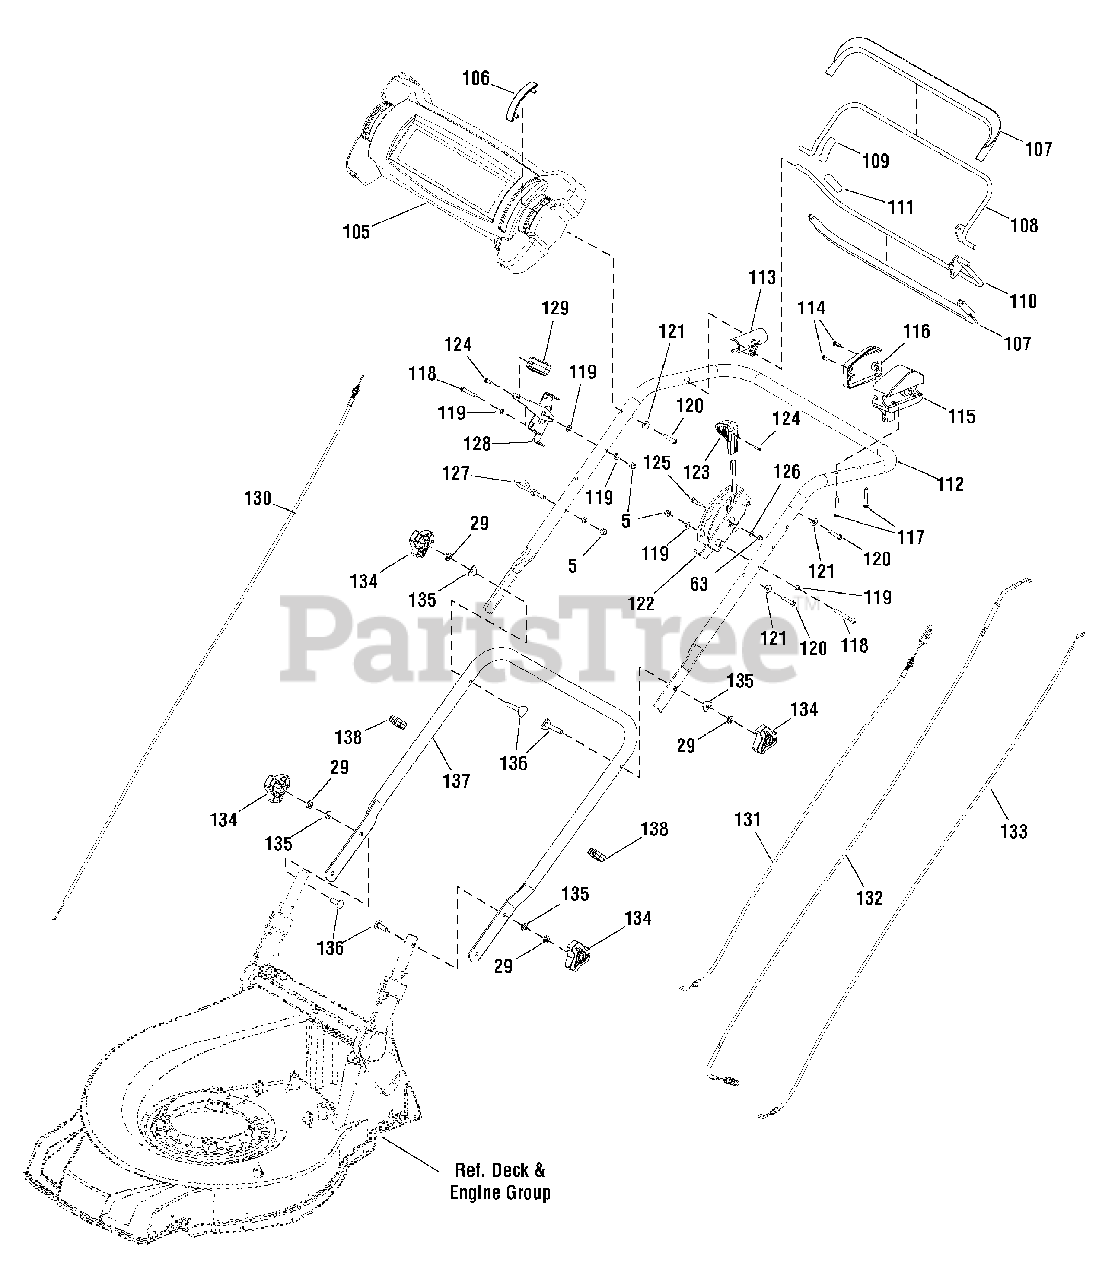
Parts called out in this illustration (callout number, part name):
5	NUT, Hex, Nylon Insert, Torque Type
29	WASHER, Spring
63	NUT, Hex, Nylon Insert, Torque Type
105	PANEL, Handle Cover
106	INSERT, Throttle Cover
107	COVER, Handle
108	LEVER, Brake
109	COVER, Brake
110	LEVER, Clutch
111	COVER, Clutch
112	HANDLE, Upper
113	HINGE
114	SCREW, Pan Head, Cross Recessed Tapping
115	CABLE BOX, Control Lever
116	COVER, Cable Box
117	SCREW, Pan Head, Cross Recessed Tapping
118	SCREW, Pan Head, Cross Recessed, H-Form
119	WASHER, Flat, C Class
120	SCREW, Pan Head, Cross Recessed Tapping
121	WASHER, Large, A-Class
122	FRAME, Speed Adjustment
123	GRIP, Speed Adjustment
124	SCREW, Pan Head, Cross Recessed Tapping
125	BOLT, Speed Adjustment Cable
126	WASHER, Flat, C-Class
127	HOOK, Start Rope
128	FRAME, Throttle
129	GRIP, Throttle
130	CABLE, Throttle
131	CABLE, Speed Adjustment
132	CABLE, Clutch
133	CABLE, Brake
134	KNOB, Lock
135	WASHER, Curved
136	BOLT, Connecting
137	HANDLE, Lower
138	CLIP, Cable
